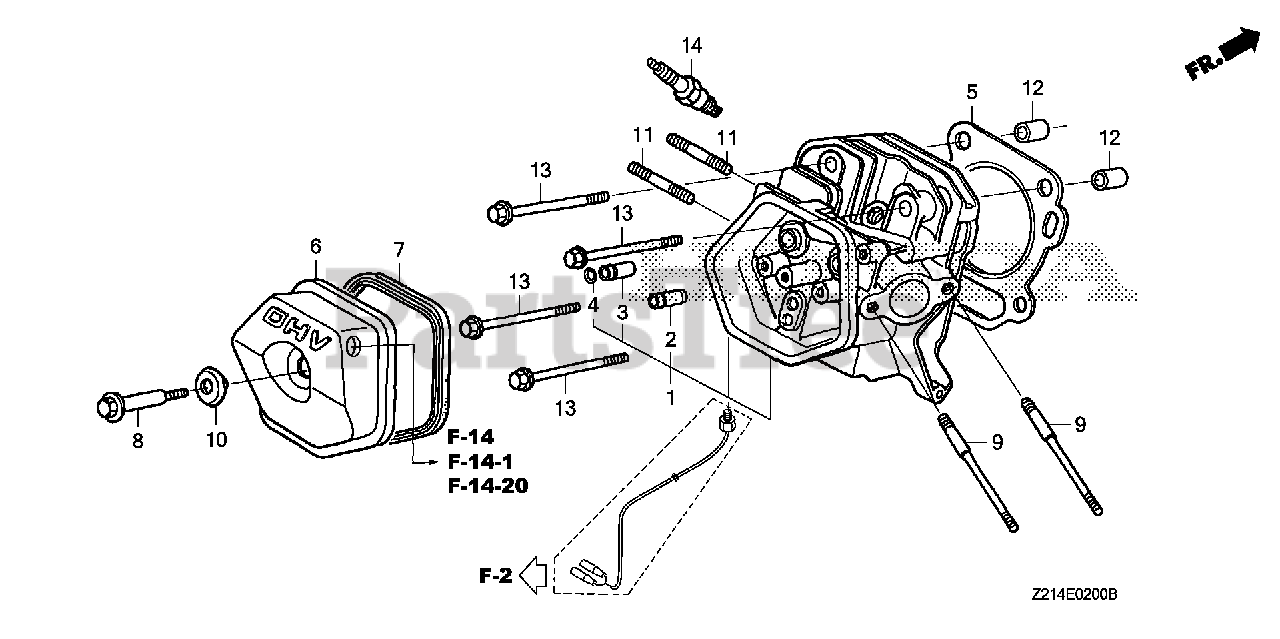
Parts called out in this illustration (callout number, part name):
1	CYLINDER HEAD
2	GUIDE, VALVE (OVER SIZE)
3	GUIDE, EX. VALVE (OVER SIZE)
4	CLIP, VALVE GUIDE
5	GASKET, CYLINDER HEAD
5	GASKET, CYLINDER HEAD (THAI LEAKLESS)
6	COVER, HEAD
7	GASKET, HEAD COVER
8	BOLT, HEAD COVER
9	BOLT, STUD (8X106)
10	WASHER, HEAD COVER
11	BOLT, STUD (8X32)
12	PIN, DOWEL (12X20)
13	BOLT, FLANGE (10X80)
14	SPARK PLUG (BPR5ES) (NGK)
